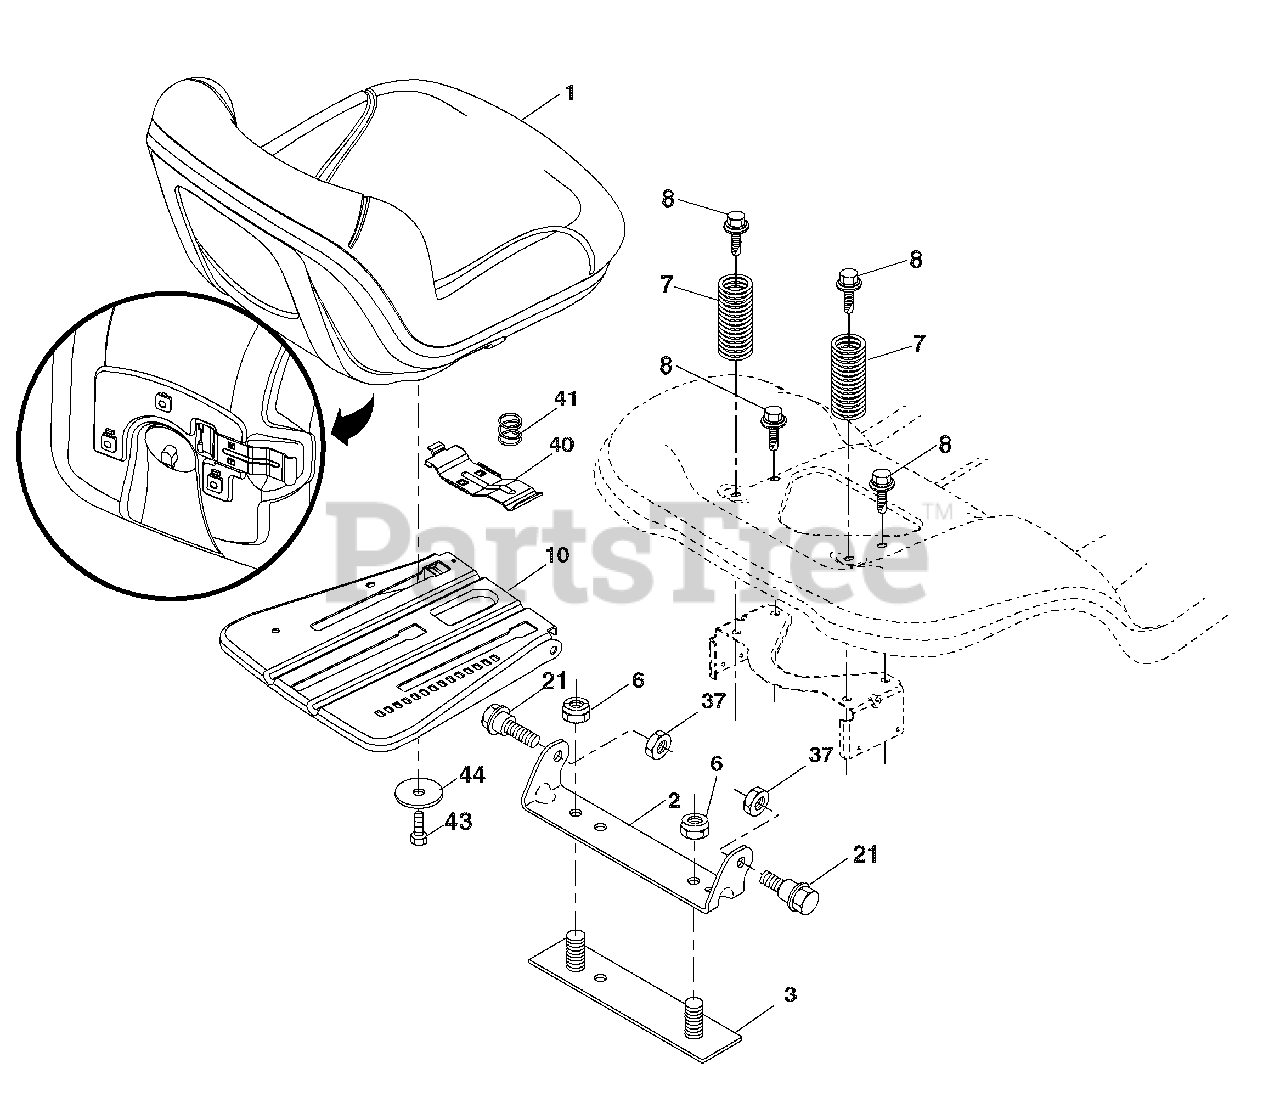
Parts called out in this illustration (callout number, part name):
1	Seat
2	Bracket Pivot Fender
3	Strap, Asm Fender
5	Clip, Push In, Hinged
6	Nut, Lock w/Ins. 3/8-16 unc
7	Spring, Seat Cprsn
8	Bolt 5/16-18 uncx 3/4 w/Sems
10	Pan, Seat
21	Bolt, Shoulder 5/16-18
37	Nut, Lock 5/16-18 unc
40	Handle Slide Seat
41	Spring Latch Seat
43	Bolt Fin Hex 3/8-16 unc x 3/4
44	Washer 13/32 x 2-3/8 x 12 Ga.
